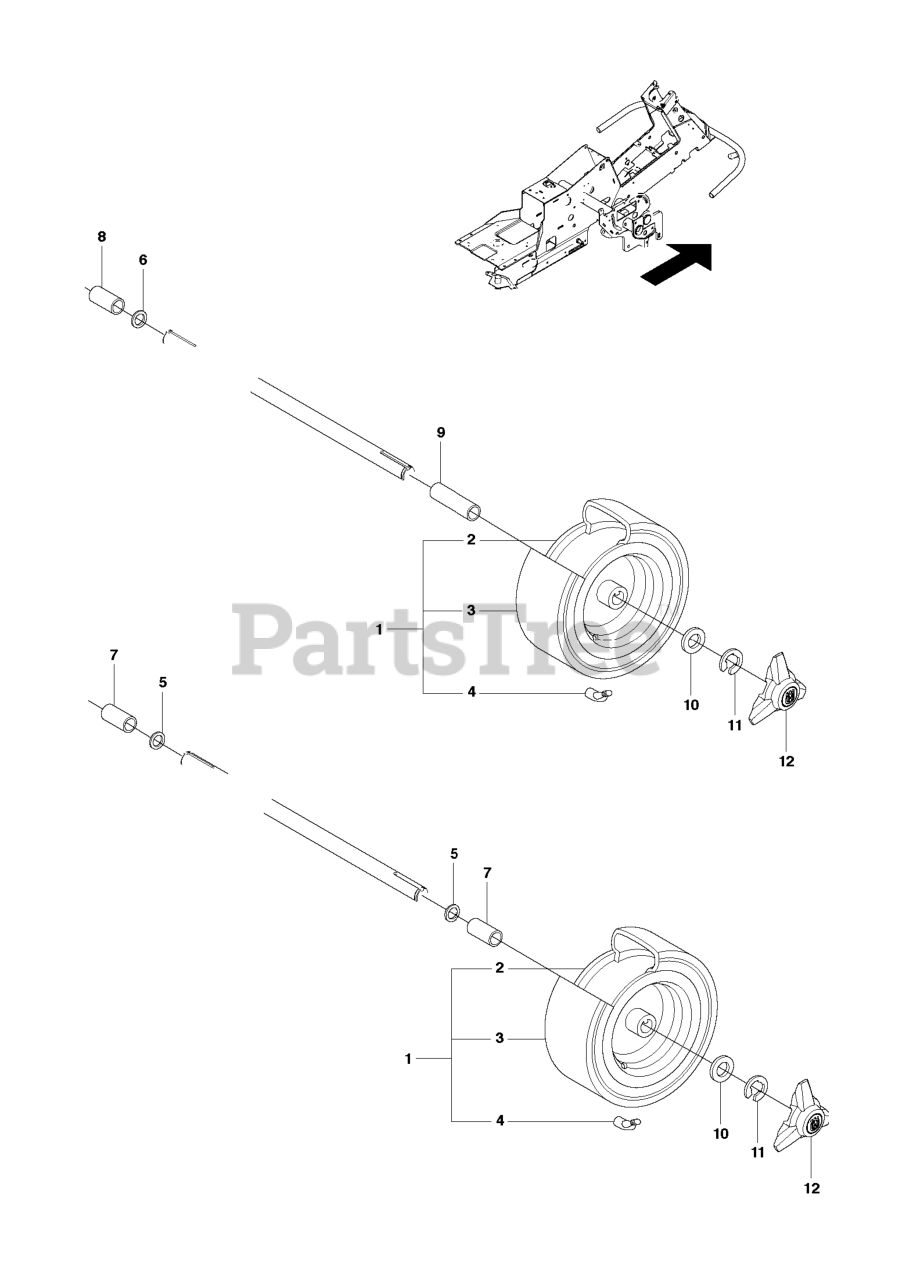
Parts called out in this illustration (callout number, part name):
3	TIRE
4	VALVE
7	SPACE SLEEVE
11	RETAINING RING
